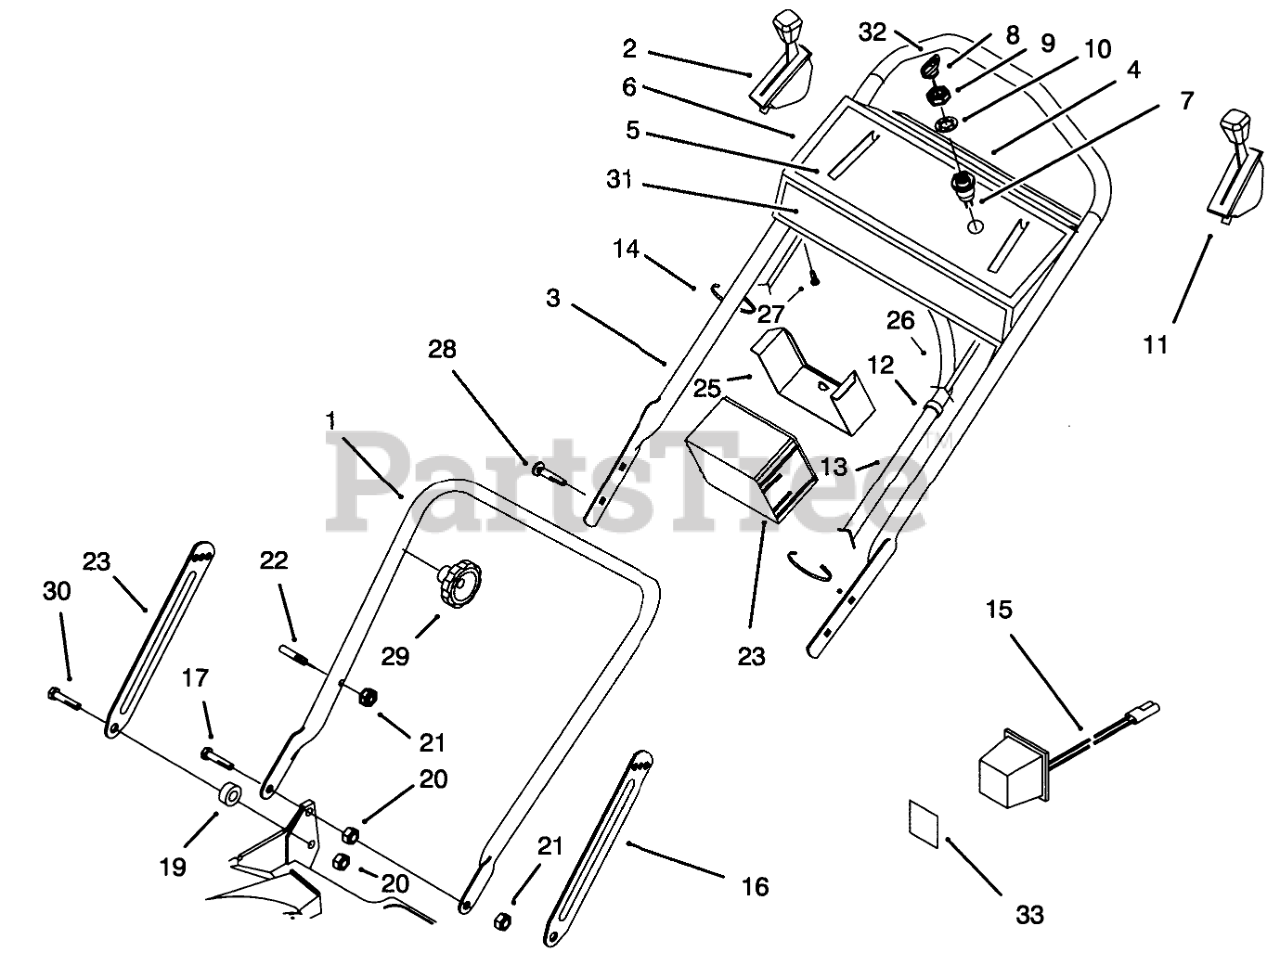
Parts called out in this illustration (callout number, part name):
1	ASM-Handle
2	CONTROL-SPEED, GROUND
3	Handle-Upper
4	DECAL-PANEL, DANGER
5	DECAL - INSTRUCTION
6	Panel-Control (Incl. Ref. #4, 5, & 31)
7	STARTER SWITCH ASM
8	KEY-IGNITION
9	NUT-HH
10	WASHER-TOOTH, INTERNAL
11	THROTTLE CONTROL
12	FITTING-RING
13	CONTROL CABLE COVER
14	TIE-CABLE
15	Charger-Battery
16	Latch-Handle
17	SCREW-SHOULDER
18	SCREW-SHOULDER
19	SPACER
20	NUT-LOCK, NI
21	NUT-LOCK, NI
22	HANDLE PIN
23	BATTERY ASSEMBLY
25	Retainer-Battery
26	Harness-Wire
27	10-16X1/2 SHWH SCREW
28	SCREW-HANDLE
30	Latch-Handle
31	DECAL - FRT PANEL
32	Grip-Foam
33	DECAL - CAUTION F/W
